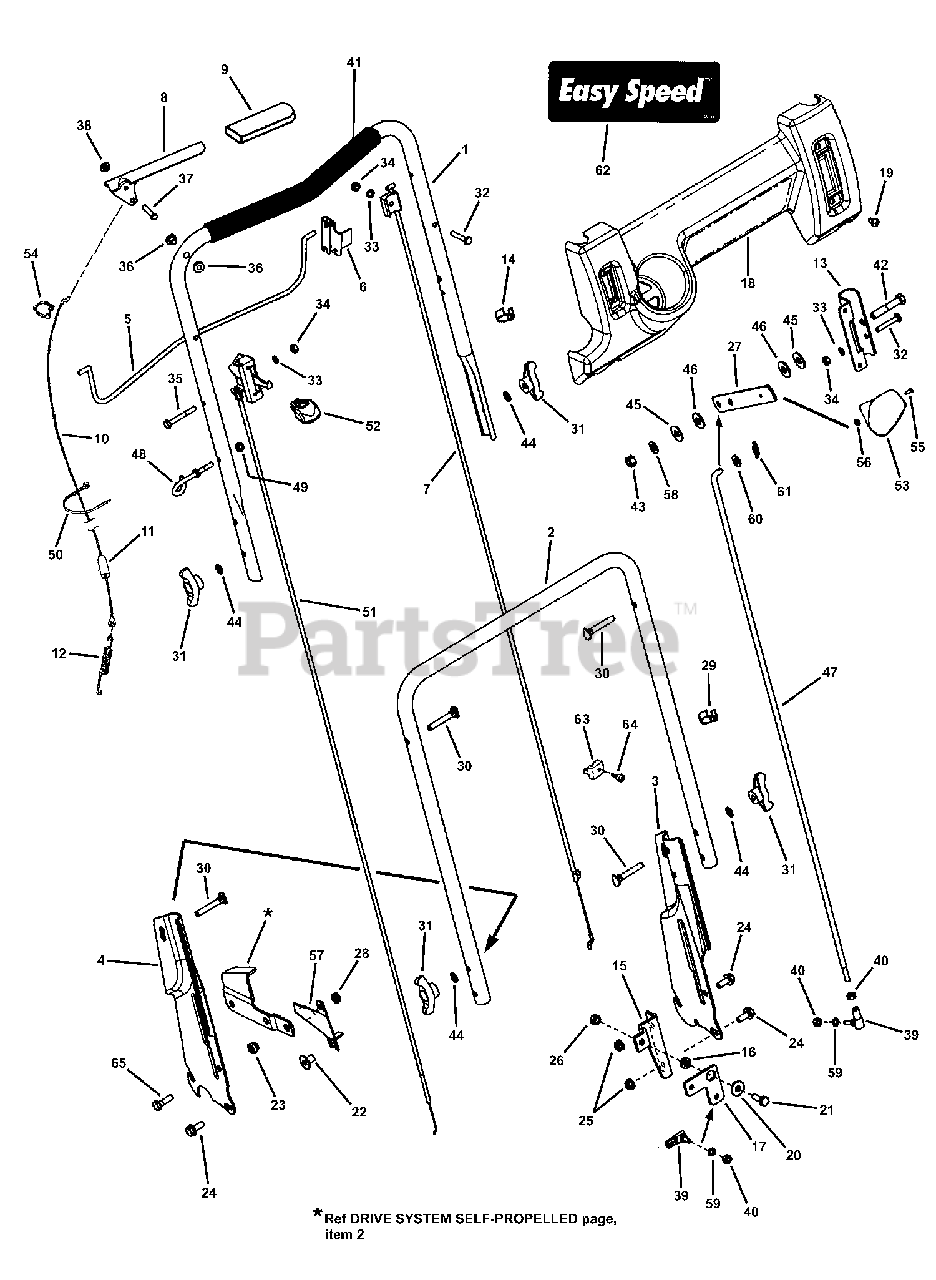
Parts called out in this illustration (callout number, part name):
1	HANDLE, Upper
2	HANDLE, Middle
3	HANDLE, Lower LH (Adjustable)
4	HANDLE, Lower RH (Adjustable)
5	BAIL, OPC Control (16.6" Wide)
6	CLIP, Zone Control
7	*CABLE, Zone Control (52-63/64" Long)
7	CABLE, Zone Control (50-31/64" Long)
7	CABLE, Zone Control (56-5/16" Long)
8	HANDLE, Clutch
9	GRIP, International Symbol
10	CABLE, Clutch Control (41-1/4" Long)
11	COVER, Vinyl
12	SPRING, Clutch- 21S
13	BRACKET, Shift
14	TIE, Wire, 1.29 long, black
15	BRACKET, Bell Crank
16	SPACER, .33 x .63 x .156
17	BELL CRANK
18	CONTROL PANEL (w/o Ground Drive Slot)
18	**CONTROL PANEL (w/o Electrical Switch Hole)
18	CONTROL PANEL (w/Electrical Switch Hole)
19	SCREW, 1/4-20 x 1/2" Pan Head Self-Tap (Torx)
20	WASHER, .33 x .88 x .09 Flat
21	SCREW, 5/16-18 x 7/8" Hex Head Cap, GR 5
22	TEENUT, 5/16-18
23	BUSHING, Differential, .328 x .625 x .41
24	BOLT, 5/16-18 x 3/4" Hex Flange Lock GR 5
25	NUT, 5/16-18 Hex Flange Lock, GR 5
26	NUT, 5/16-18 Hex Center Lock
27	LEVER, Shift
28	NUT, 5/16-24 Hex Center Lock GR 5
29	CLIP, Wiring Harness
30	SCREW, 5/16-18 x 1-7/8" Curved Head GR 2
31	KNOB, 5/16-18 Wing (Black)
32	SCREW, 1/4-20 x 1-1/2 Hex Head Cap GR 5
33	WASHER, 1/4" Internal Tooth Lock
34	NUT, 1/4-20 Hex
35	SCREW, 1/4-20 x 2" Hex Head Cap, GR 5
36	BUSHING, .27 x .35 x .4 Flange
37	PIN, 1/4 x 1-1/2"
38	PUSH-NUT, 1/4"
39	BALL JOINT, 1/4-28
40	NUT, 1/4-28 Hex
41	FOAM GRIP, 15" long
42	SCREW, 3/8-16 x 2" Hex Head Cap, GR 5
42	SCREW, 3/8-16 x 1-3/4" Hex Head Cap, GR 5
43	NUT, 3/8-16 Hex Center Lock
44	WASHER, 5/16" Internal Tooth Lock
45	WASHER, 7/16" Flat
46	WASHER, Nylon
47	ROD, Speed Control (1/4-28 thread)
48	GUIDE, Rope (1/4-20 thread)
49	NUT, 1/4-28 Hex GR 5 or B
50	CABLE-TIE, 7"
51	*THROTTLE CONTROL, .48 x .61
51	*THROTTLE CONTROL, 6.0 KWV
52	THROTTLE KNOB
53	KNOB, Shift
54	CLAMP, 7/8" Double Cable
55	SCREW, #8-32 x 1/2" Cross Recess Filister Head Machine
56	NUT, #8-32 Hex
57	BELT GUIDE, Lower
58	WASHER, Belleville
59	WASHER, 1/4" Internal Tooth Lock
60	WASHER, 3/8" Flat
61	COTTER PIN, 5/16 Self Lock
62	DECAL, Easy Walk
63	CLAMP, Casing
64	SCREW,#10-32 x 5/8" Self-Tap
65	SCREW, 5/16-24 x 1" Hex Head Cap GR 5
